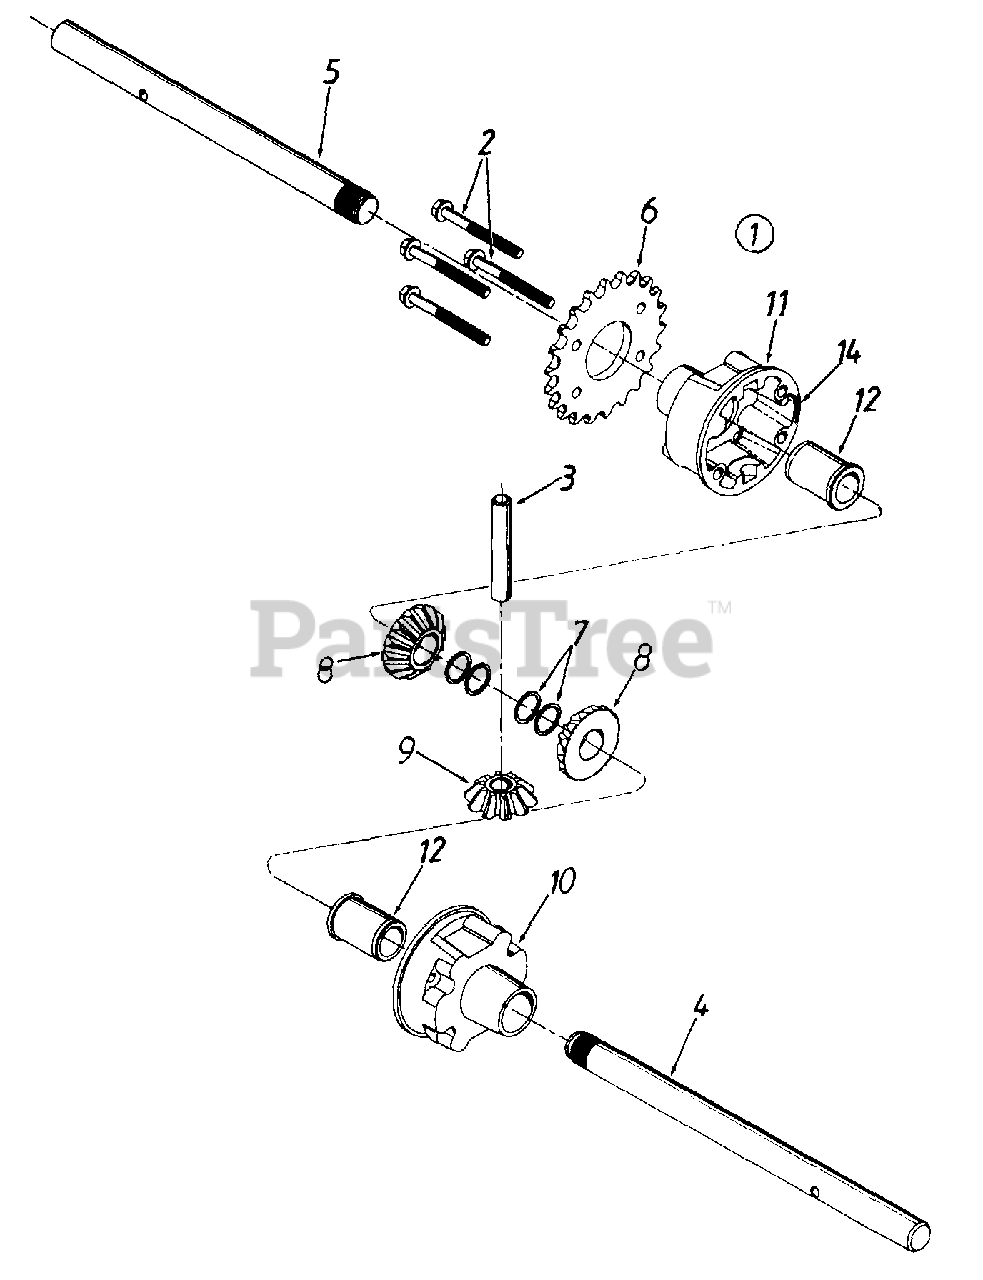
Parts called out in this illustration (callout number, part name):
1	DIFFERENTIAL ASSY COMPLETE
2	SCREW-HEX
3	SHAFT-CROSS
4	AXLE-SHAFT 10.95" LONG
5	AXLE-SHAFT 9.82" LONG
6	SPROCKET 22 T
7	RING-RETAINING (2 PER AXLE)
8	GEAR-DIFFERENTIAL 14T
9	GEAR-DIFFERENTIAL 107
10	HOUSING-DIFFERENTIAL RH
11	HOUSING-DIFFERENTIAL LH
12	BEARING-FLANGE
